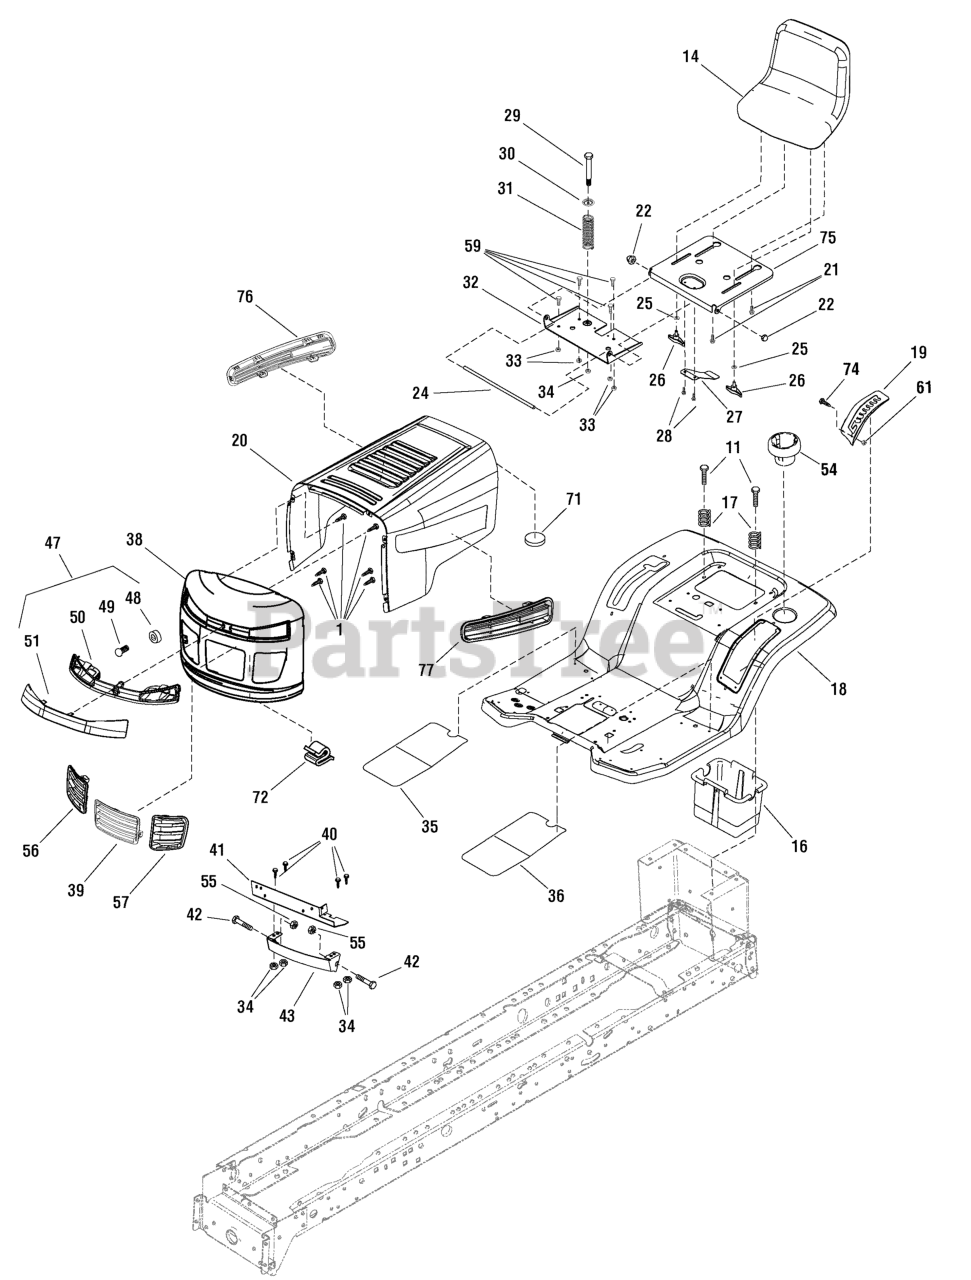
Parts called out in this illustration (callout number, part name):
1	SCREW, Thread Forming
11	CAPSCREW, 5/16-18 x 3/4
14	SEAT, High Back
16	CONTAINER, Battery
17	SPRING, Compression
18	DECK, Seat
19	PLATE, Index
21	BOLT, Shoulder 5/16-18 x 5/8
22	CAP, Push On
24	ROD, Pivot
26	BOLT, Wing 5/16-18 x 1/2
27	LEAF SPRING
28	SCREW, 1/4-14 x 3/8
29	BOLT, Shoulder 1/4-20 x 5/16
30	WASHER, Cup
31	SPRING, Compression
32	BRACKET, Seat Pivot
33	NUT, Nylock 5/16-18
34	NUT, Nylock 1/4-20
35	MAT, Right
36	MAT, Left
39	INSERT, Center Grille
40	SCREW, .25-20 X0.59 HEX
41	BRACKET, Support
42	BOLT, Shoulder
43	BRACKET, Lower Pivot
47	HEADLIGHT ASSEMBLY
48	SOCKET, Lamp
49	BULB, Light
50	HOUSING, Light
51	LENS, Light
54	HOLDER, Cup
55	NUT, Centerlock, 3/8-16
56	INSERT, Right Grille
57	INSERT, Left Grille
59	BOLT, Hex, 5/16-18 x 5/8
61	NUT, Flange Lock 1/4-20
74	SCREW, Shoulder #10-24
75	SUPPORT, Seat
76	INSERT, Right Hood
77	INSERT, Left Hood
